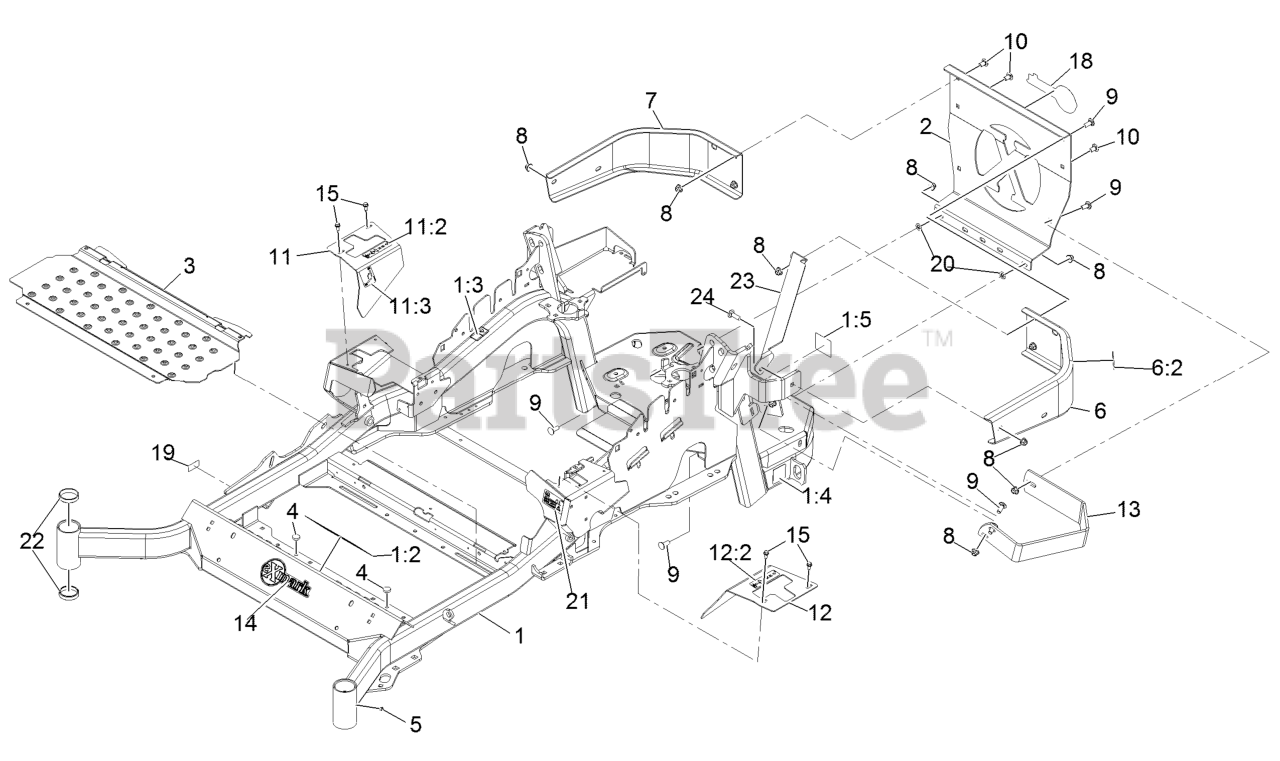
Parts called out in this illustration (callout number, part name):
1:2	DECAL-DANGER
1:3	DECAL-WARNING
1:4	DECAL-HAZARD, PINCHED FINGER
1:5	DECAL-SPARK ARRESTER
2	PLATE,REAR GUARD
6	LH BUMPER ASM
6:2	DECAL-WARNING
7	BUMPER-RH
8	NUT-HF, NI
9	SCREW-CARR
10	SCREW-CARR
11	RH MOTION CONTROL COVER ASM
11:2	DECAL-CONTROL, MOTION
11:3	DECAL-PARK BRAKE, CE
12	LH MOTION CONTROL COVER ASM
12:2	DECAL-CONTROL, MOTION
13	GUARD-MUFFLER
14	DECAL-EXMARK LOGO
15	SCREW-HWH
18	DECAL-EXMARK LOGO
19	Decal-Patent Ttco.Com
20	NUT-PUSH
21	DECAL-FUEL FILL, CE
22	CUP-BEARING
24	BOLT-CARR
